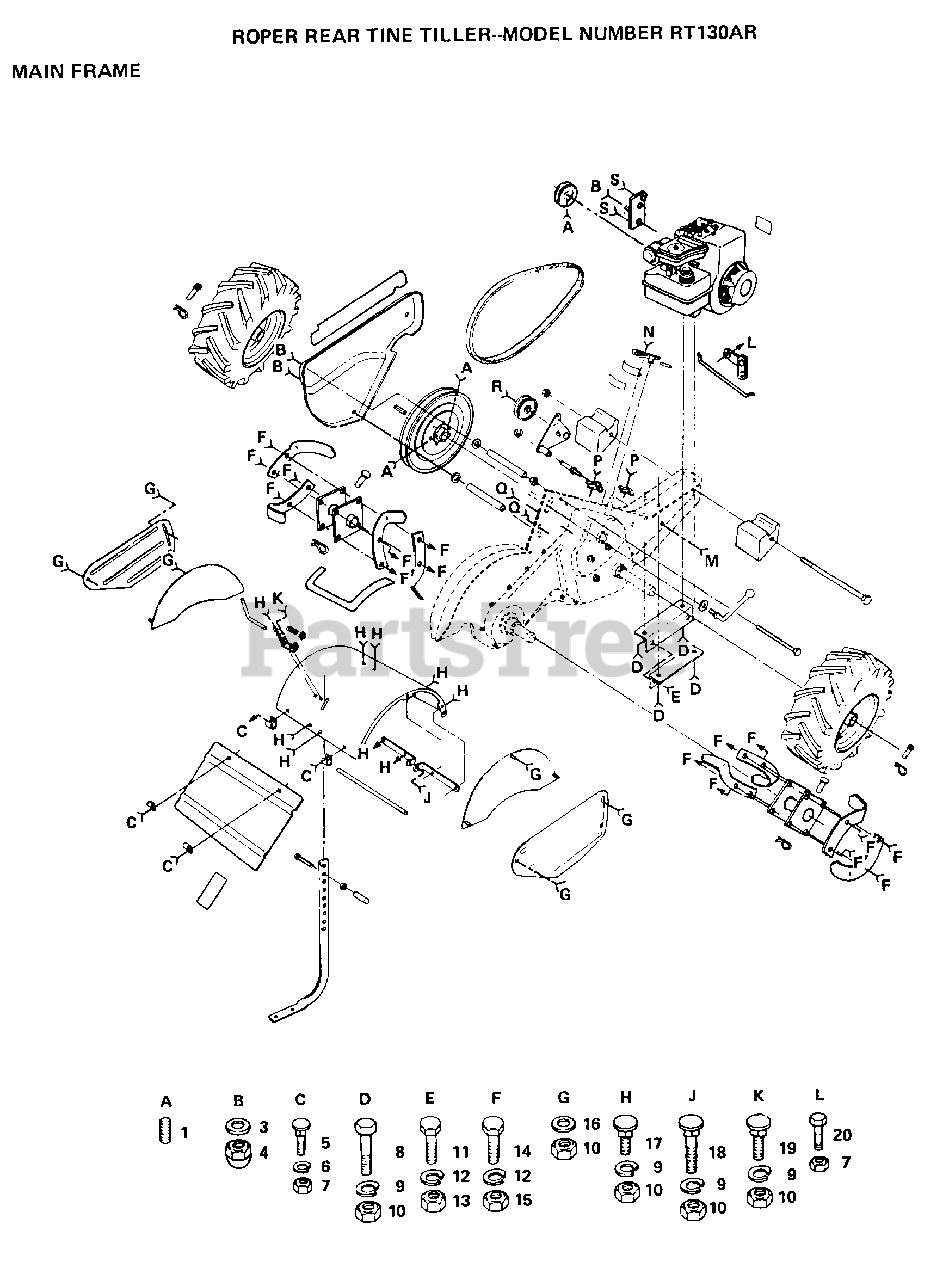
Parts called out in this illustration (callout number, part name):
1	SET SCREW
3	WASHER
4	NUT TI
5	BOLT
6	LOCKWASHER
8	BOLT.HEX.5/16-1.5
9	LOCKWASHER
10	NUT.HEX.5/16-18
11	BOLT
12	LOCKWASHER
13	NUT.HEX.3/8-16UNC
14	BOLT
16	WASHER
17	BOLT
18	BOLT CRT
19	BOLT
